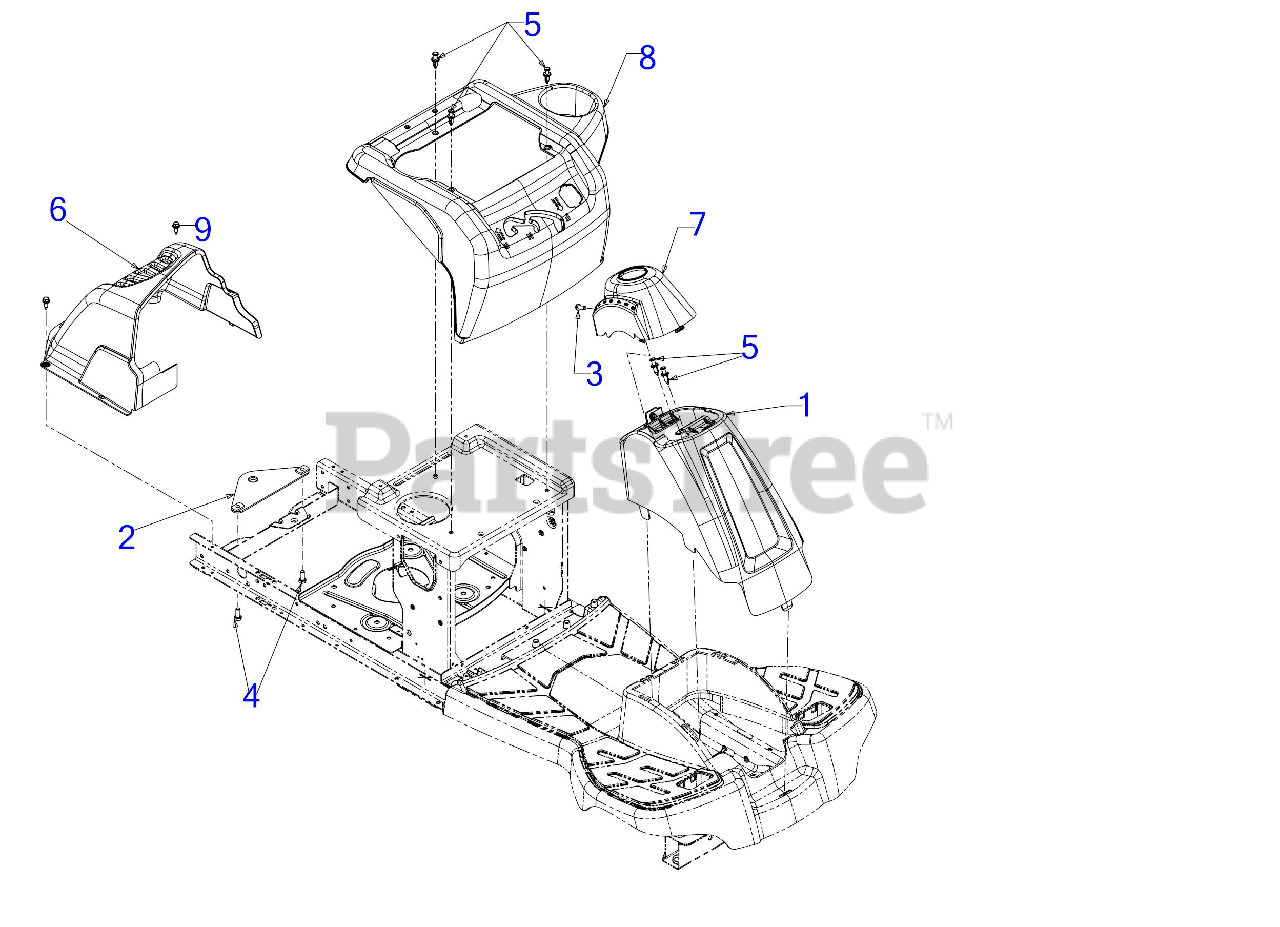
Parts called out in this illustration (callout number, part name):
1	COLUMN COVER ASSEMBLY (MTD RED)
3	SCREW 1/4-20X.75
4	SCREW 5/16-18 x .75 GR5
5	PLASTIC RIVET
6	DRIVE COVER
7	COLUMN STEERING CAP
8	FENDER (MTD RED)
9	SHOULDER SCREW
